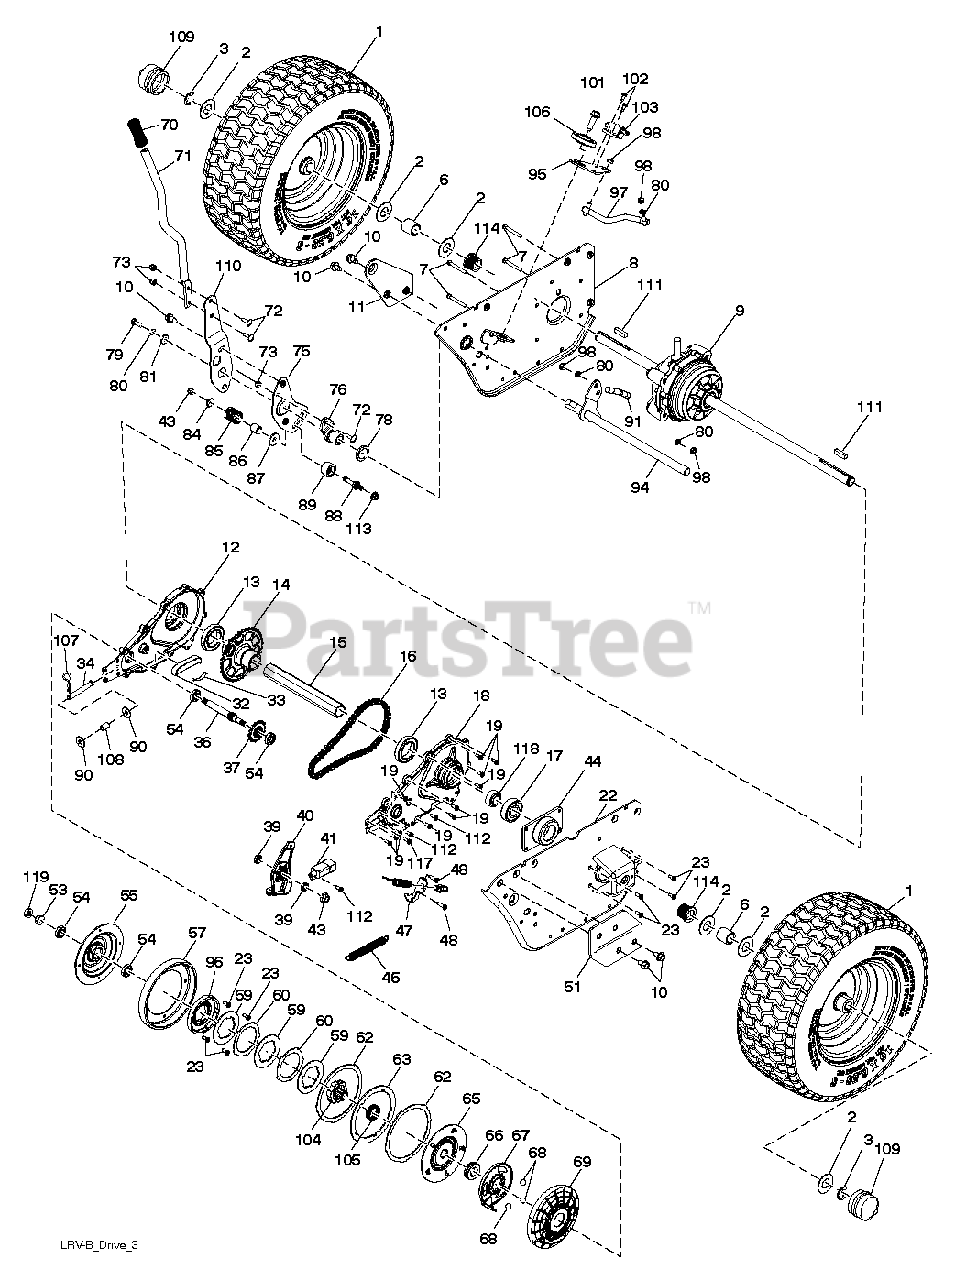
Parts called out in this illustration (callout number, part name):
1	WHEEL.TUBE.16X5.50-8.MS613
3	E-RING LT
6	SPACER, AXLE PVST
7	HCS.1/4-20 X 1-3/4 GR 5 ZD
8	WELDMENT.SUPPORT.AXLE.RH
9	RP SUBASM.DRIVE.FINAL.LRVB
10	SCREW
11	BRACKET.SUPPORT.RH
12	RP CASE.CHAIN RH
13	BEARING.BALL.6207-2RS
14	SPROCKET DRIVEN.37. TOOTH
15	TUBE.INPUT.HEX.LRVB
16	CHAIN.#35.56.PITCHES
17	BEARING.BALL.6204-3-2RS
18	CASE.CHAIN.LH
19	SCREW.10-24X5/8.PAN.HEAD TORX
22	WELDMENT.SUPPORT.AXLE
23	SCREW.TORX.#10-14X1/2
32	BLOCK.TENSION.CHAIN
33	SPRING ADJUSTER.TENSION
34	PIN.CLEVIS.5/16X2 1/2
36	SHAFT.INPUT.CLUTCH
37	SPROCKET.SPLINED.14.TOOTH
39	BEARING.BALL.689ZZ
40	ARM.BRAKE
41	SWITCH INTERLOCKT
43	NUT.71038.31-18.HEX.NYLOCK
44	COVER.END.HEX
45	SPRING.DRIVE
47	BRACKET MOUNT.CABLE.LRV.B
48	SCREW.HEX.HEAD.WASH.10-24X1.00
51	BRACKET SUPPORT.LH
53	NUT LOCK FLG 3/8-16 UNC
54	BEARING.BALL.6901-2RS
55	COVER.CLUTCH.WHEEL
57	WHEEL.FRICTION
59	PLATE.CLUTCH.DRIVE
60	PLATE.PRESSURE.DRIVE
62	PLATE.CLUTCH.BRAKE
63	PLATE.PRESSURE.BRAKE
65	PLATE.PRESSURE.MASTER.LRVB
66	BEARING THRUST.20MM
67	PLATE THROWOUT
68	BEARING BALL.LOOSE
69	COVER.CLUTCH.LRVB
70	GRIP.HANDLE.LIFT.PVC.BLACK
71	TUBE.SHIFT.LRVB
73	NUT.CROWNLOCK.1/4
76	HUB.SHIFT
78	SPACER.NYLON.
80	LOCKWASHER
81	WASHER LT
85	SPRING.FRICTION.PACK.
86	BUSHING.PACK.FRICTION.FD2
87	WASHER.PLASTIC
88	STUD.PACK.FRICTION
89	STUD.PACK.FRICTION.FD2
90	WASHER
91	SUBASM.LINK.SHIFT
94	WELDMENT.SHIFT.FD2
95	PLATE.SHIFT
96	DRUM.MULTI-DISC.CLUTCH
97	SUBASM.LINK.SHIFT.PRIMARY
98	NUT LOCK CENTER 1/4 -28 FNTHD
101	SCREW 3/8-16 X 1-1/2
104	HUB.CENTER
105	SPRING.WAVE.C125-H5
106	SPACER.RETAINER
108	BUSHING.5/16 ID.X7/160DX1/2
109	CAP.HUB.AXLE.LRVA/B
110	BRACKET, SHIFTER FLEX
111	SQUARE KEY
112	SCREW.TORX.#10-14X.750
113	NUT LOCK HEX FLANGE 5/16-18
114	BEARING.FLANGE
117	SCREW.TORX.SHOULDER 10-14
119	NUT
